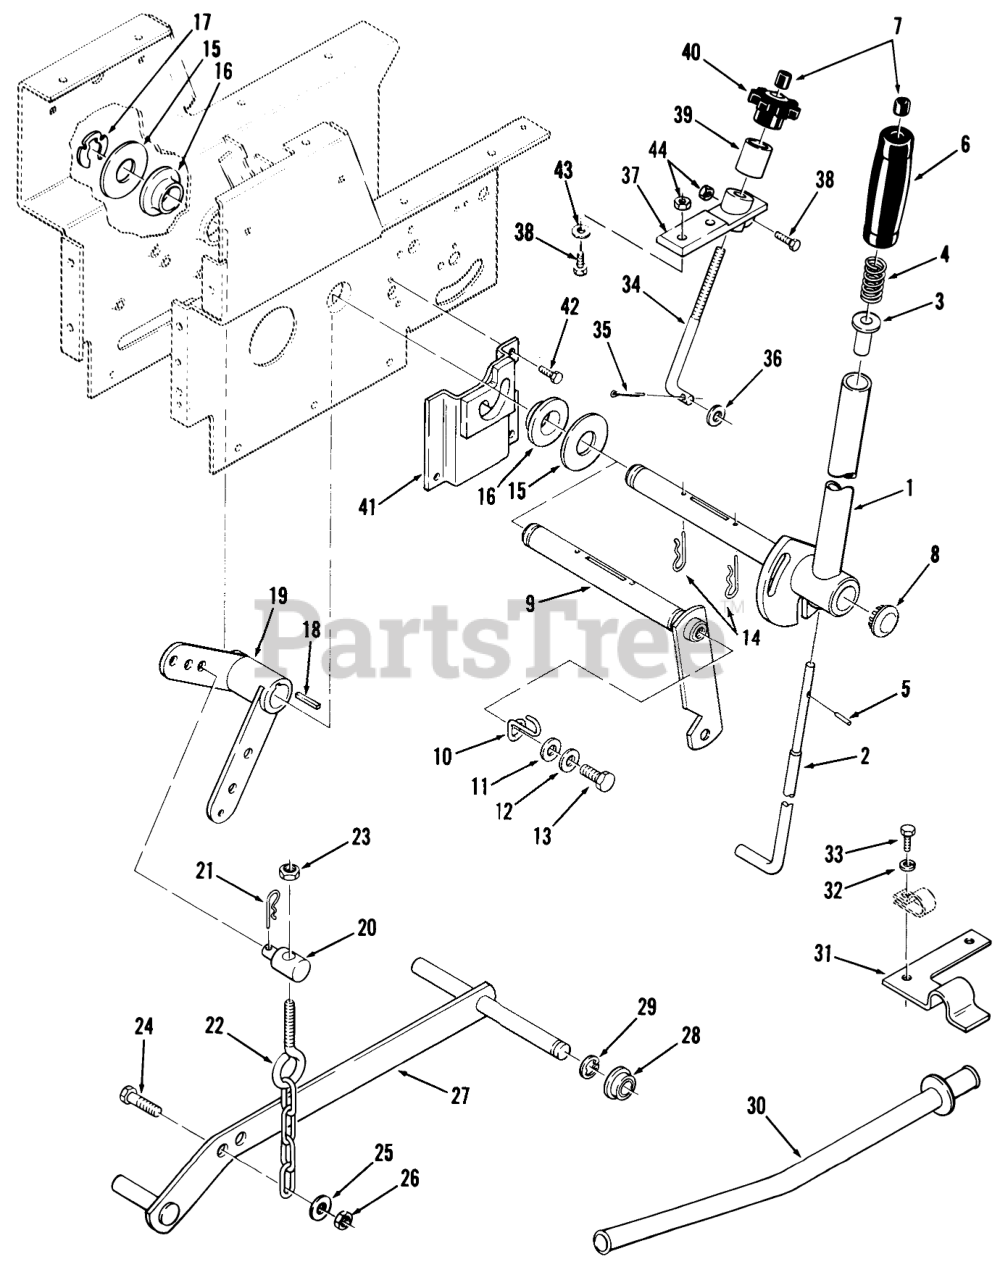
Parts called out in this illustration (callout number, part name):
1	Lift Lever
2	ROD-LATCH LIFT
3	RETAINER-SPRING
4	SPRING-COMPRESSION
5	PIN-SPIROL
6	HANDGRIP
7	CAP-ROD, PLUNGER
8	PLUG
9	Lift Lever
10	Indicator
11	WASHER 5/16 SAE
12	Lockwasher
13	Screw
14	Pin-Cotter
15	WASHER
16	BEARING-FLANGE
17	Retainer
18	KEY-SQUARE
19	Bellcrank
20	TRUNNION-LIFT
21	Hairpin
22	CHAIN-LIFT
23	Nut
24	Bolt
25	WASHER 5/16 SAE
26	Nut
27	ASSY LIFT BAR R
28	BUSHING
29	E Ring
30	TUBE ASSY COMPLET R
31	Clamp-Tube
32	LOCKWASHER
33	Bolt
34	Rod
35	Pop Rivet
36	WASHER -4
37	Casting
38	Bolt
39	Sleeve
40	KNOB-LIFT CONTROL
41	Latch Bracket
42	SCREW
43	WASHER 5/16 SAE
44	Nut
